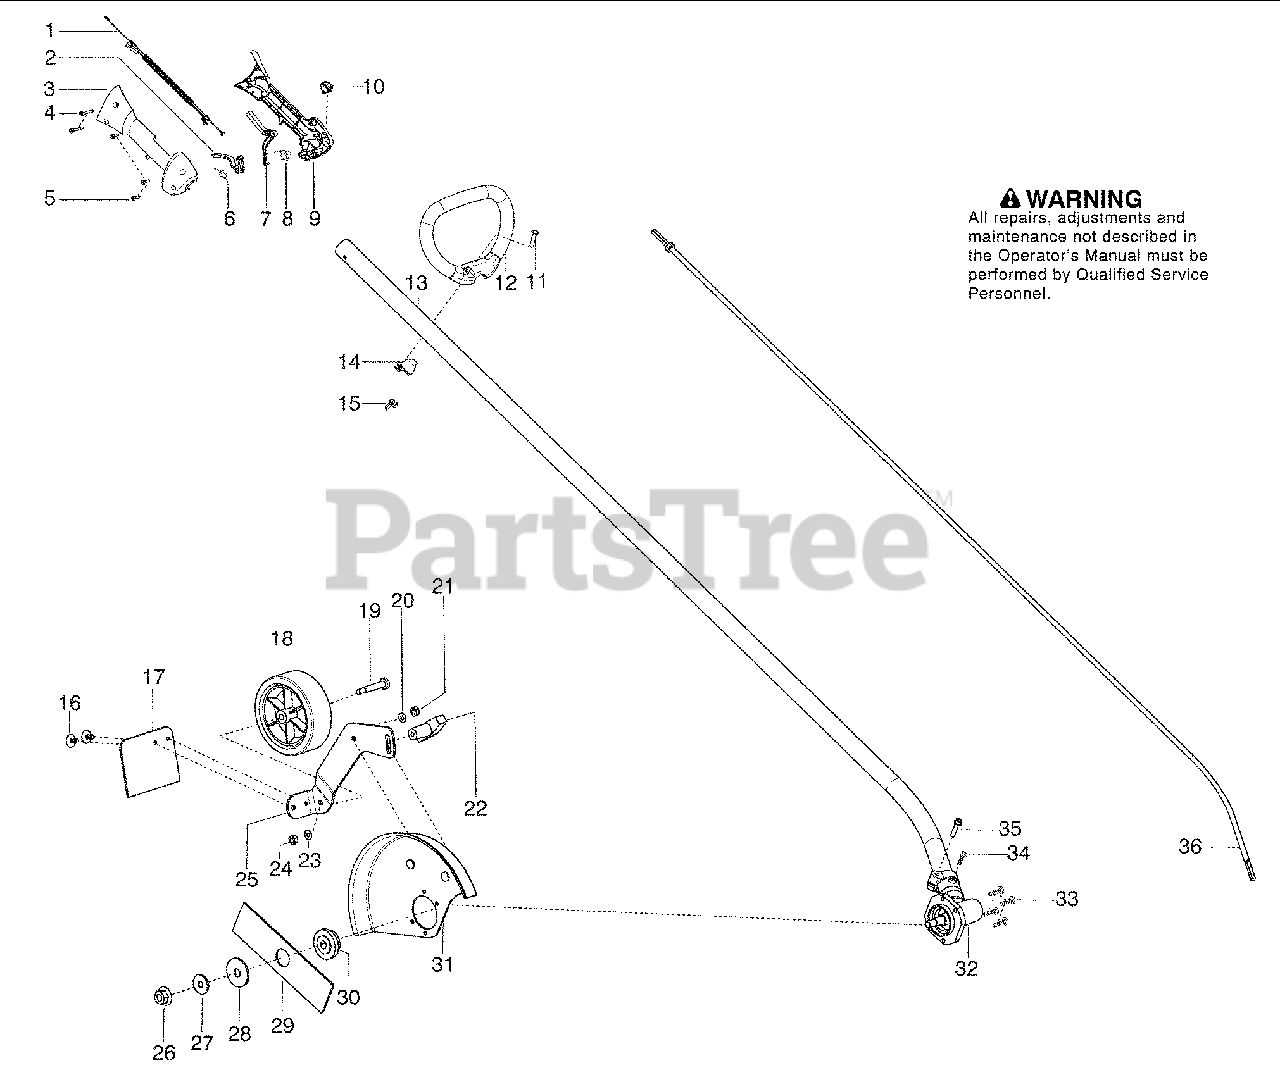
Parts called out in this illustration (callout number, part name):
1	Assy-Cable/Wire Harness
3	Housing-Throttle (RH)
6	Spring-Trigger
7	Lockout-Throttle
8	Spring-Lockout
9	Housing-Throttle (LH)
10	Kit-Switch
12	Handle-Assist
13	Kit-Driveshaft Edger
14	Clamp-Handle
15	Wingnut
16	Fastener - Mud Flap
17	Kit-Mud Flap
18	Wheel - 4"
19	Bolt-Shoulder Axle
25	Bracket-Wheel Adjustment
26	Nut-Flange L.H.
27	Washer-Belleville Spring
28	Washer-Flat
31	Kit-Edger Guard
32	Kit-Edger Gearbox
34	Screw
36	Flexshaft
